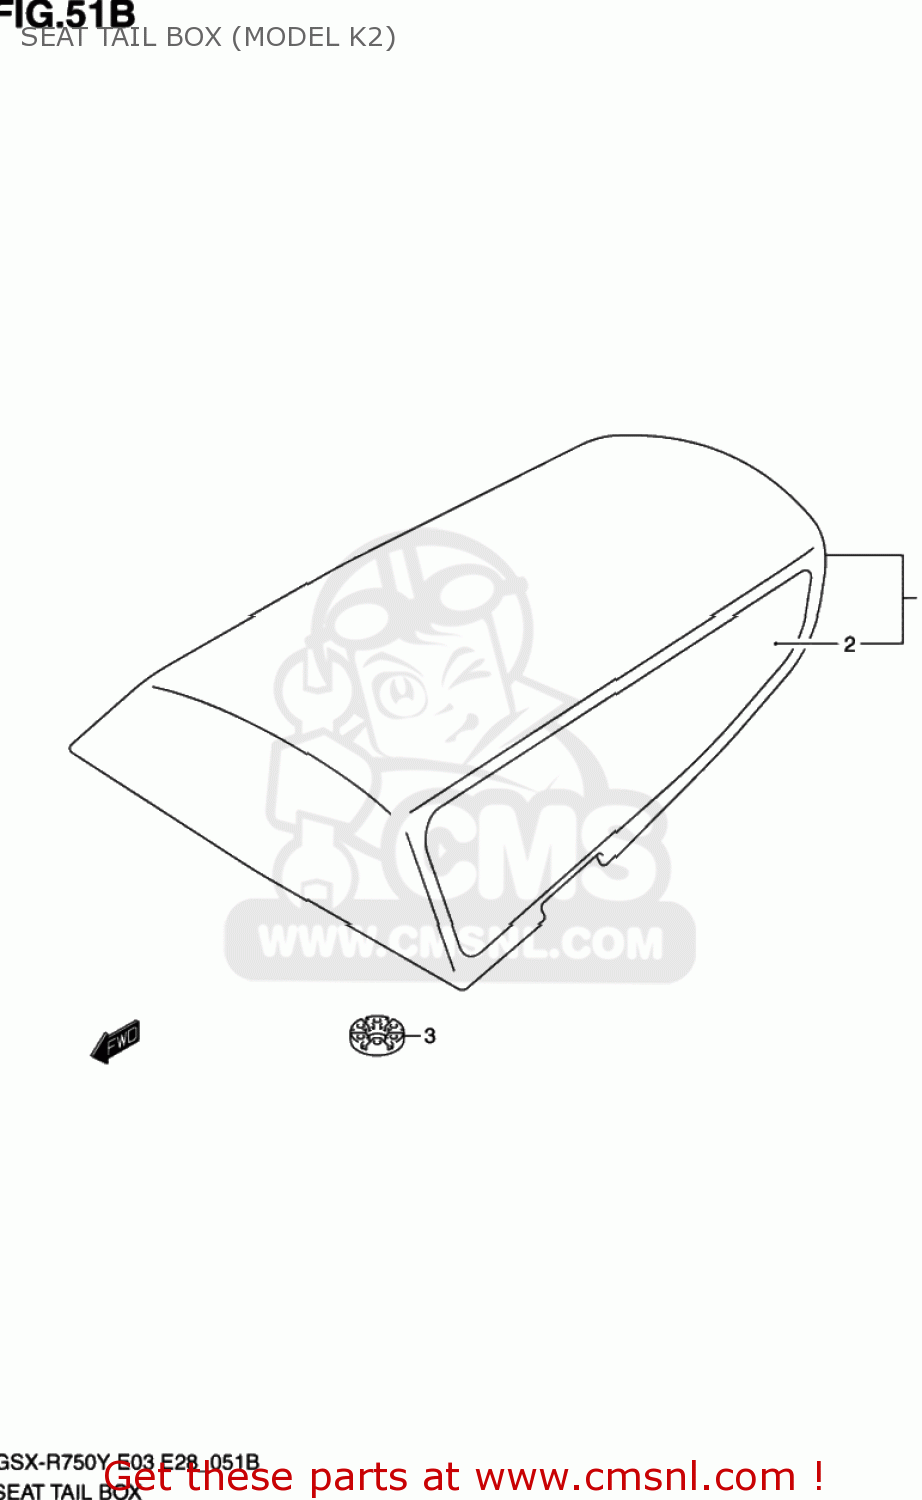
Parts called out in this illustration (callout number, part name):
1	BOX ASSY,SEAT TAIL(RED)
2	TAPE SET,BOX SEAT TAIL(BLACK)
3	CUSHION
